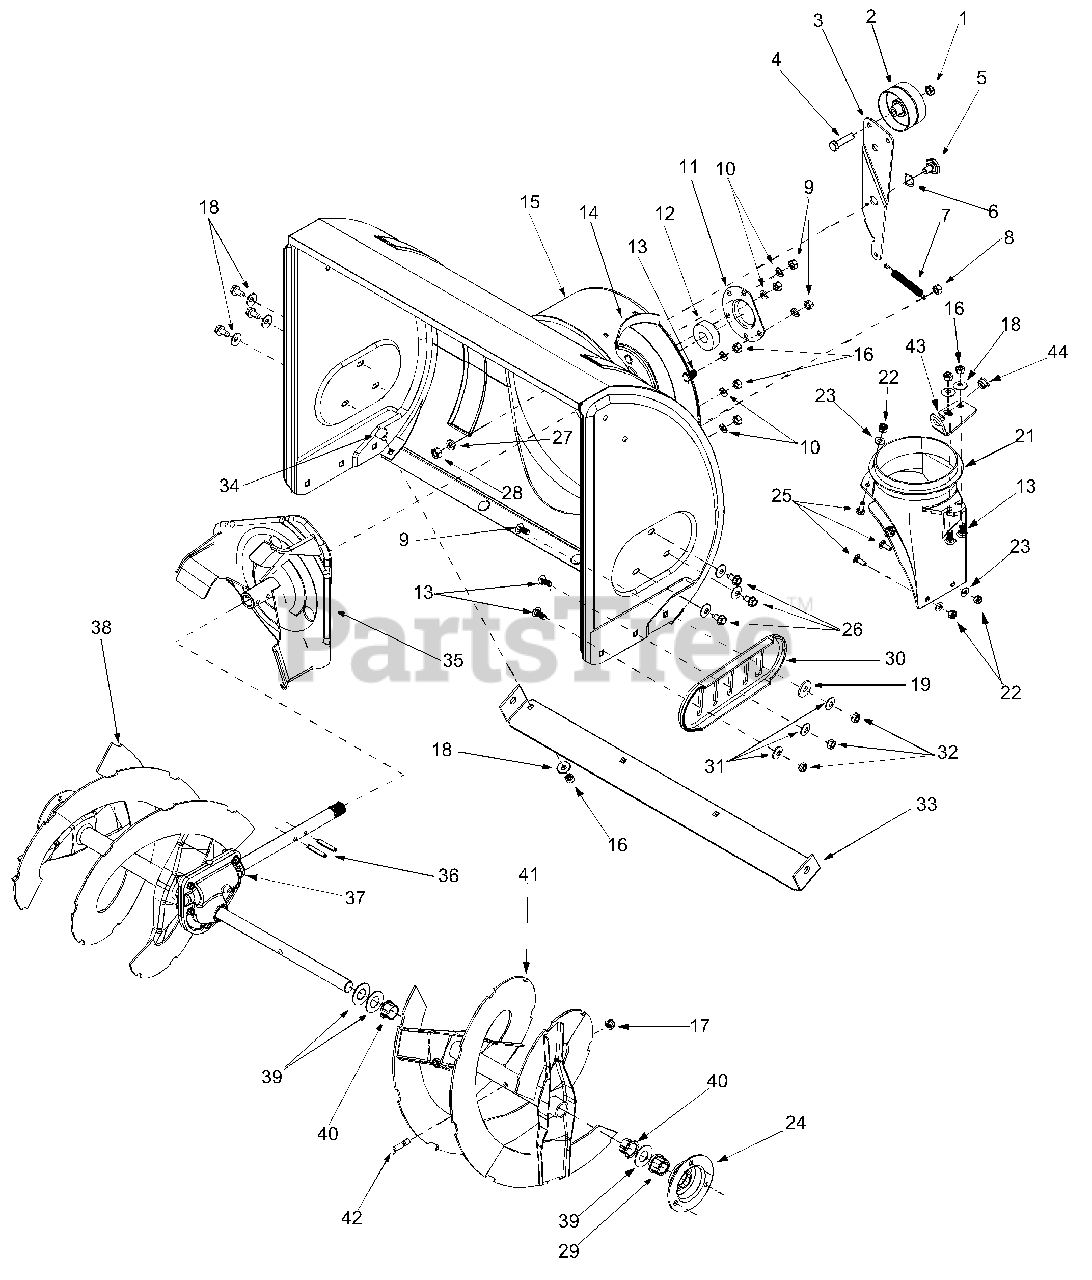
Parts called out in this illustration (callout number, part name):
1	Lock Jam Nut 3/8-24
2	Flat Idler
4	Hex Cap Screw 3/8-24 x 1.50
5	Shoulder Screw
6	Flat Washer .656 ID x 1.25 OD
7	Extension Spring
8	Hex Nut 5/16-18
9	Carriage Bolt, 5/16-18 x 1.00
10	Lock Washer 5/16
11	Housing
12	Ball Bearing
13	Carriage Bolt, 5/16-18 x .75
17	Lock Nut 5/16-18
18	Belleville Washer
19	Flat Wshr, .344 ID x 1.125 OD
21	Chute Adapter
22	Hex Lock Nut 1/4-20
23	Flat Washer
25	Carriage Screw 1/4-20 x .75
26	Hex Screw 5/16-18
27	Lock Washer 3/8
28	Hex Nut 3/8-16
29	Hex Flange Bearing
31	Bell Washer
32	Hex Nut 5/16-18
34	Carriage Bolt 5/16-18 x 1.00
37	26" Gear Assembly
39	Flat Washer
40	Flange Bushing
44	Bushing
